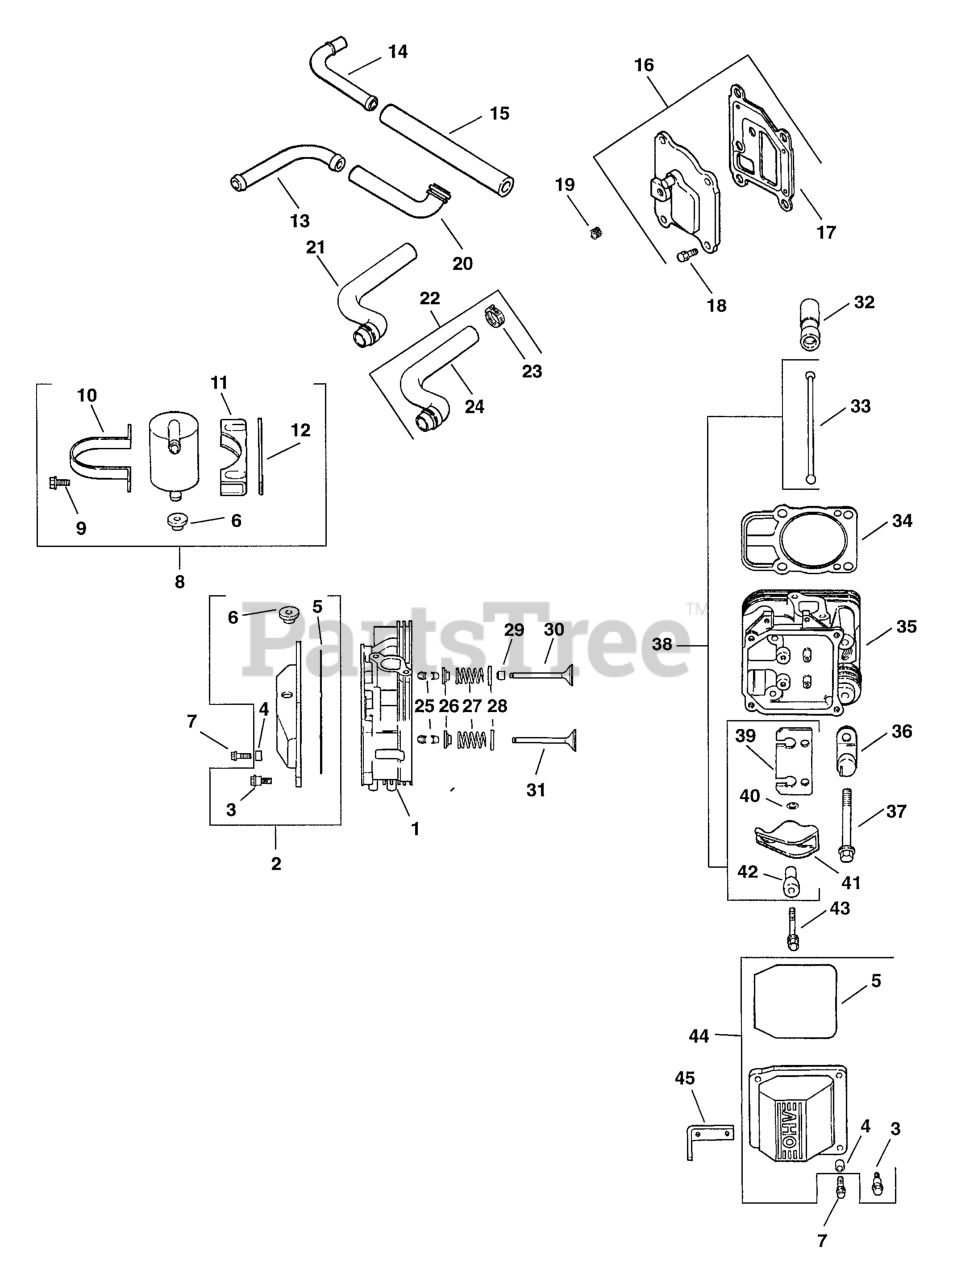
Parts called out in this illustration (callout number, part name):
1	Head Assembly, #1 Cylinder
2	Kit, Valve Cover - Breather
3	Screw, Hex. Cap - Shoulder M6x1.0x23
6	Grommet, Rubber
8	Kit, Breather Separator
9	Screw, Hex. Flange M5x0.8x16
9	Screw, Hex. Cap 8-18x1/2"
10	Strap, Breather
11	Bracket, Breather Separator
15	Hose, Breather
16	Kit, Breather Cover W/Gasket
17	Gasket, Breather
18	Screw, Hex. Flange M6x1.0x20
25	Kit, Retainer (4)
26	Cap, Valve Spring
27	Spring, Valve
28	Retainer, Spring
30	Valve, Intake (Std.)
30	Valve, Intake (.25)
31	Valve, Exhaust (Std.)
31	Valve, Exhaust (.25)
32	Lifter, Valve
33	Rod, Push
34	Gasket, Cylinder Head
35	Head Assembly, #2 Cylinder
37	Screw, Hex. Flange M10x1.5x91
38	Kit, Valve Train
39	Plate, Guide
40	Washer, Plain 6 Mm
41	Arm, Rocker
42	Pivot, Rocker Arm
43	Screw, Hex. Flange M6x1.0x34
44	Kit, Valve Cover - Plain
45	Strap, Lifting
